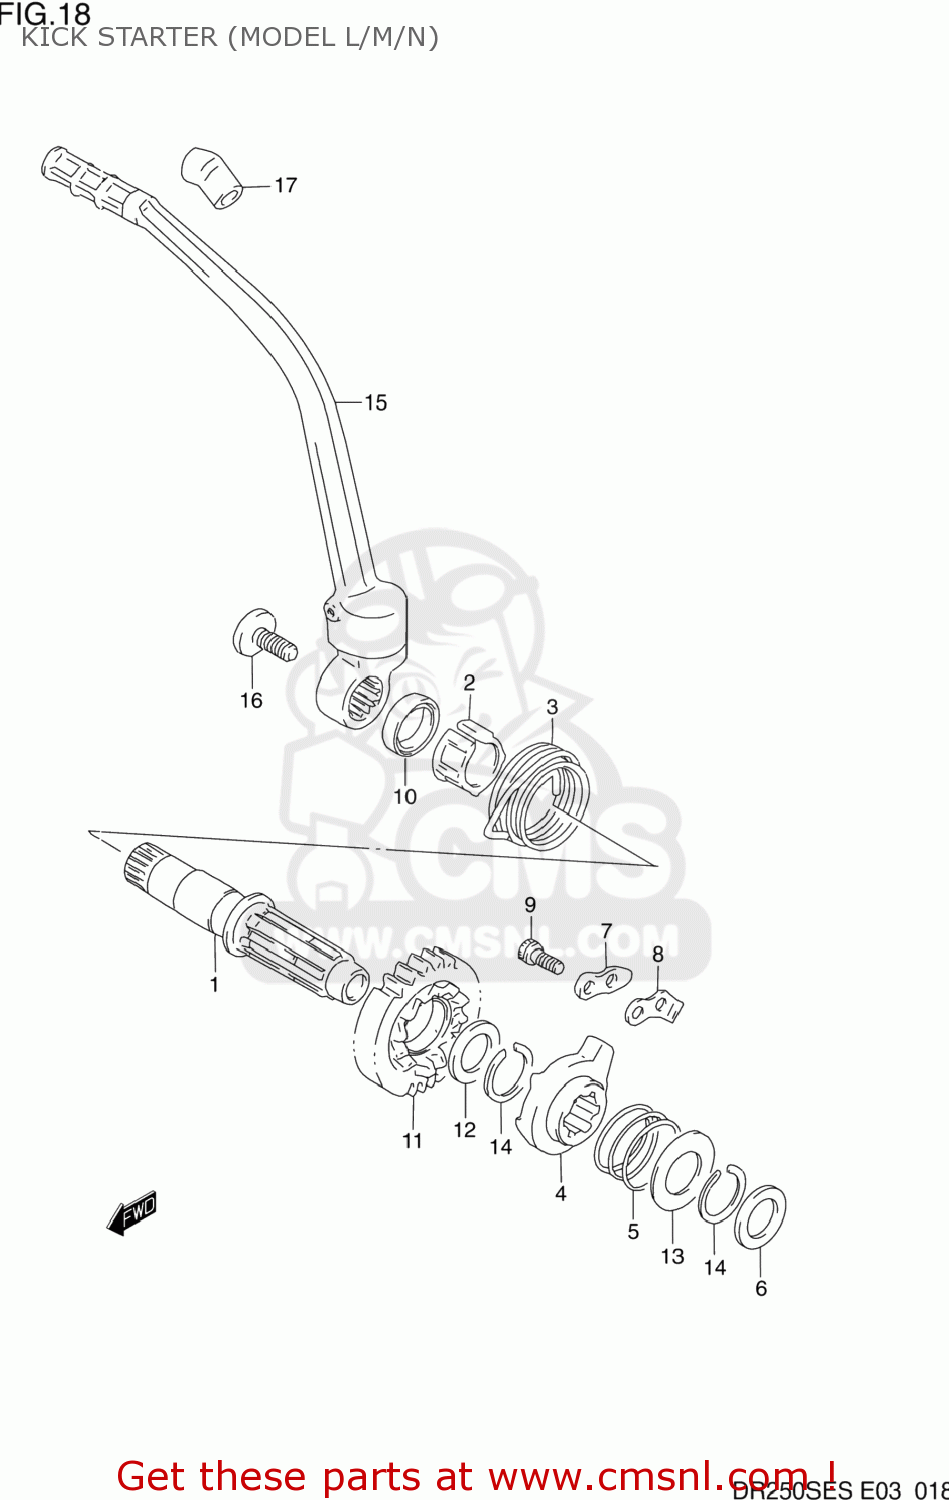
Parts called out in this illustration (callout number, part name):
1	SHAFT,KICK STARTER
2	GUIDE,KICK STARTER SFT SPRING
3	SPRING
4	STARTER,KICK
5	SPRING
6	WASHER,THRUST
7	GUIDE,KICK STARTER
8	STOPPER,KICK STARTER
9	BOLT,KICK START STOPPER
10	SEAL,OIL(20X27X6)
11	GEAR,KICK STARTER NO.2
12	SHIM
13	WASHER,THRUST
14	CIRCLIP
15	LEVER ASSEMBLY,KICK STARTER
16	BOLT(8X14)
17	COVER,KICK STARTER LEVER
